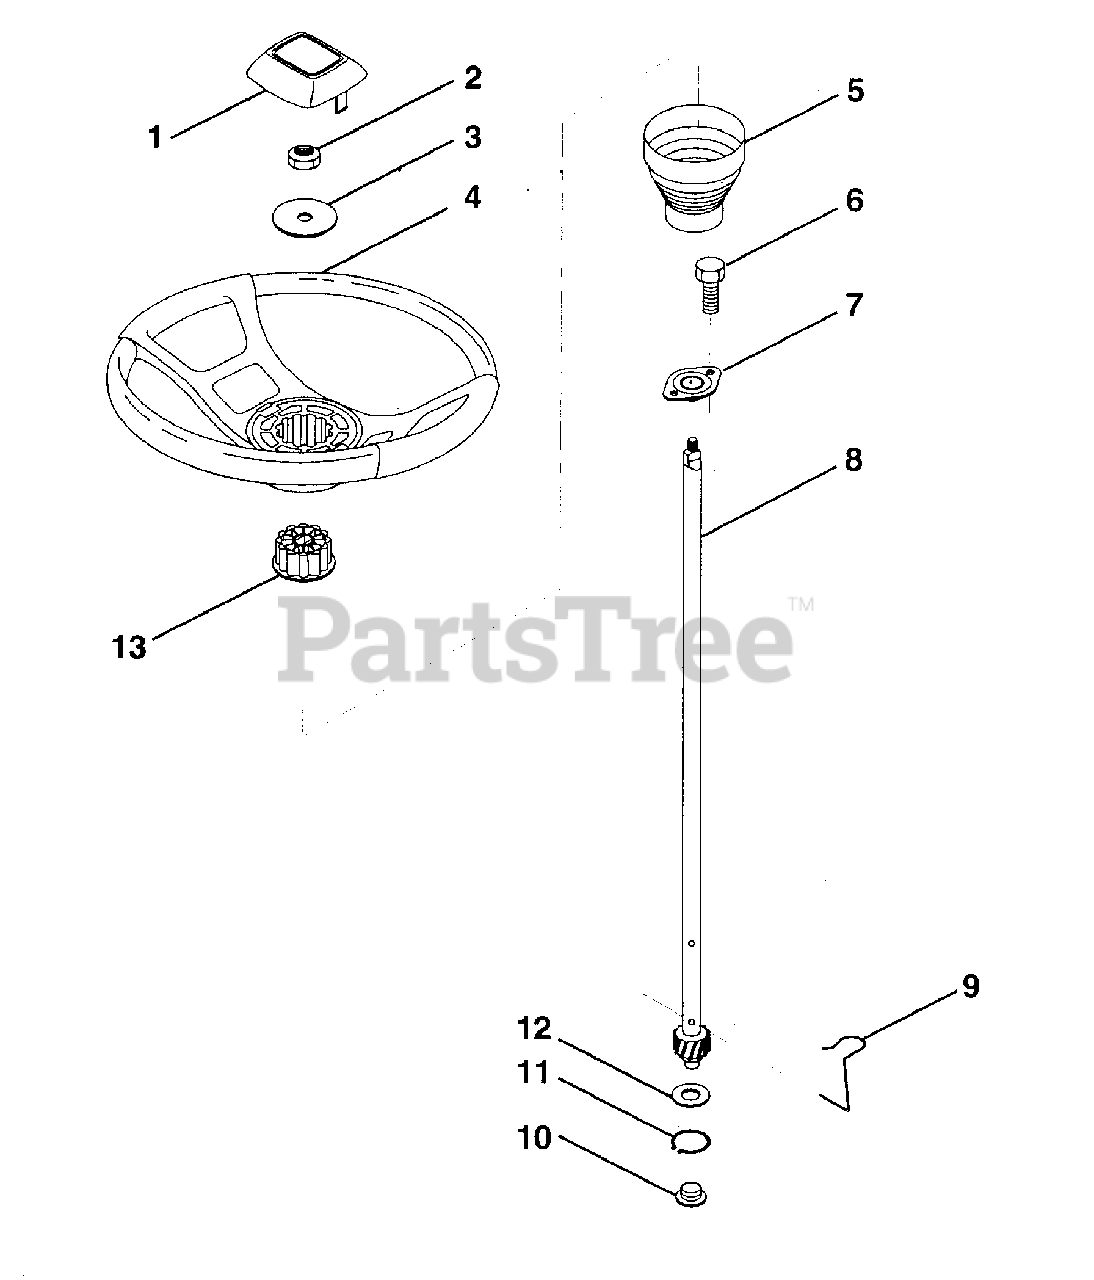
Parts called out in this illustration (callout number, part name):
1	Insert, Wheel, Steering
2	Nut, Lock 3/8-24 UNF
3	Washer 12/32 x 2-3/8 x 8 Ga.
4	Wheel, Steering
5	Sleeve, Steering
6	Screw, Hex #10-16 x 1/2 TY-B
7	Bushing, Steering
8	Shaft, Steering
9	Clip, Steering
10	Bushing, Lower, Steering
11	Ring, Retaining
12	Washer 21/32 x 1 x 16 Ga.
13	Adaptor, Wheel, Steering
